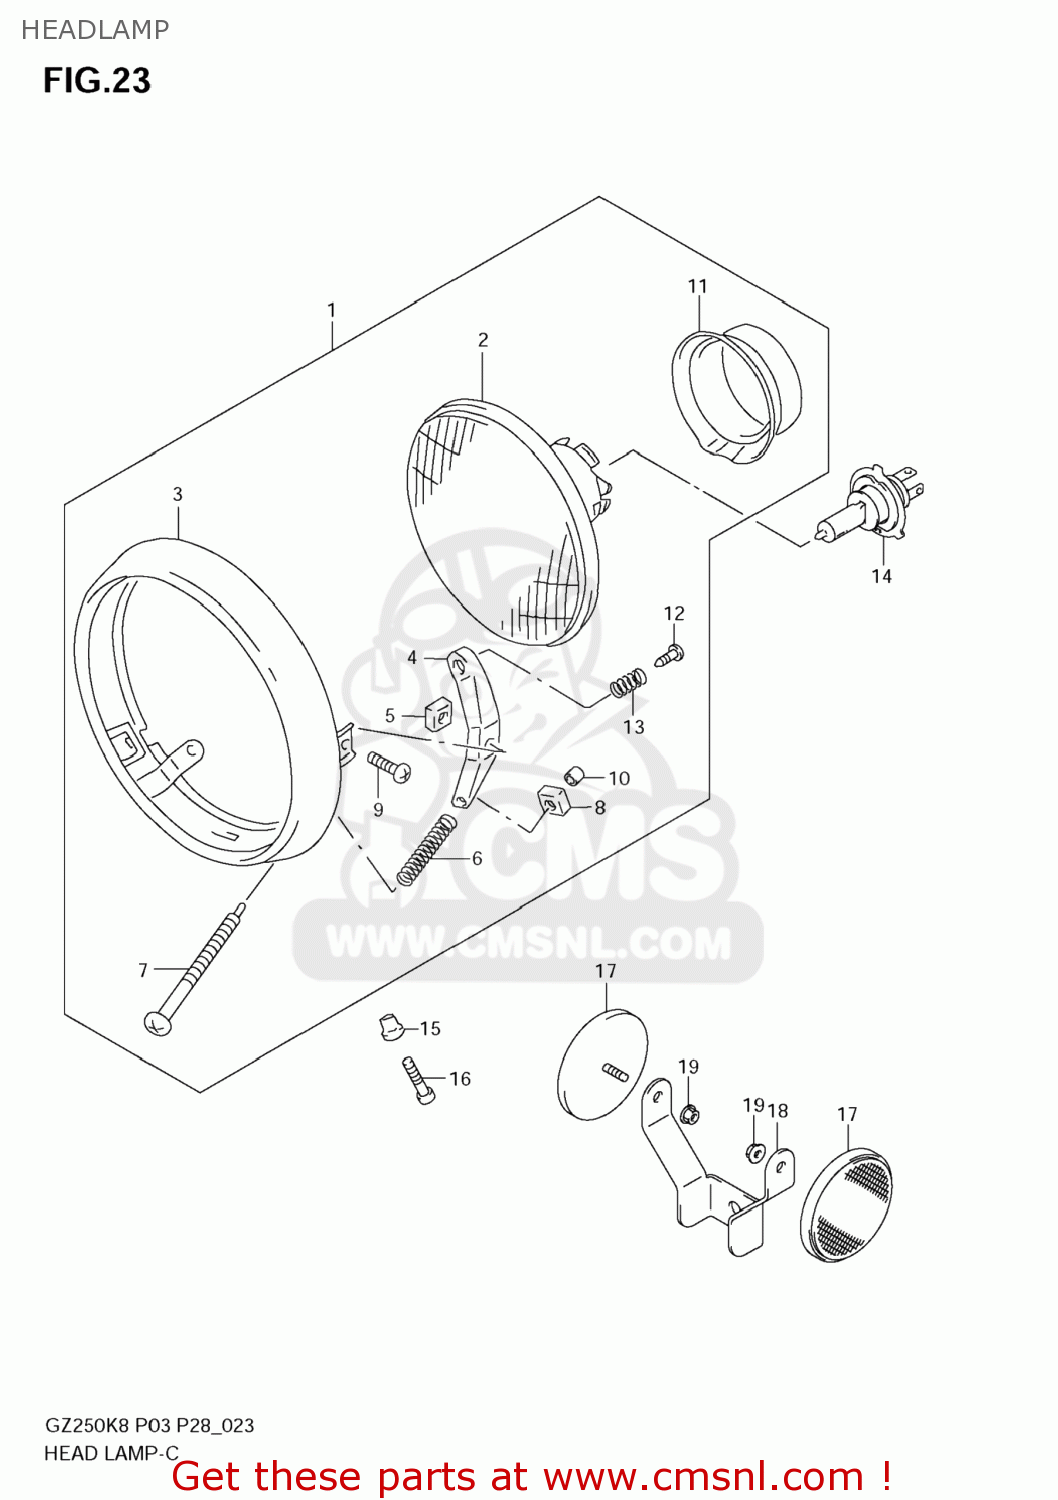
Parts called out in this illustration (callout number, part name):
1	HEADLAMP ASSY
2	UNIT ASSY
3	RIM,HEAD LAMP
4	STAY
5	NUT
6	SPRING
7	SCREW
8	NUT,HEADLAMP ADJUST
9	SCREW
10	CAP,SCREW
11	COVER,SOCKET
12	SCREW
13	SPRING
14	BULB(12V60/55W,H4)
15	SPACER,HEADLAMP
16	SCREW
17	REFLECTOR,REFLEX
18	BRACKET,FR SIDE DEFLECTOR
19	NUT
